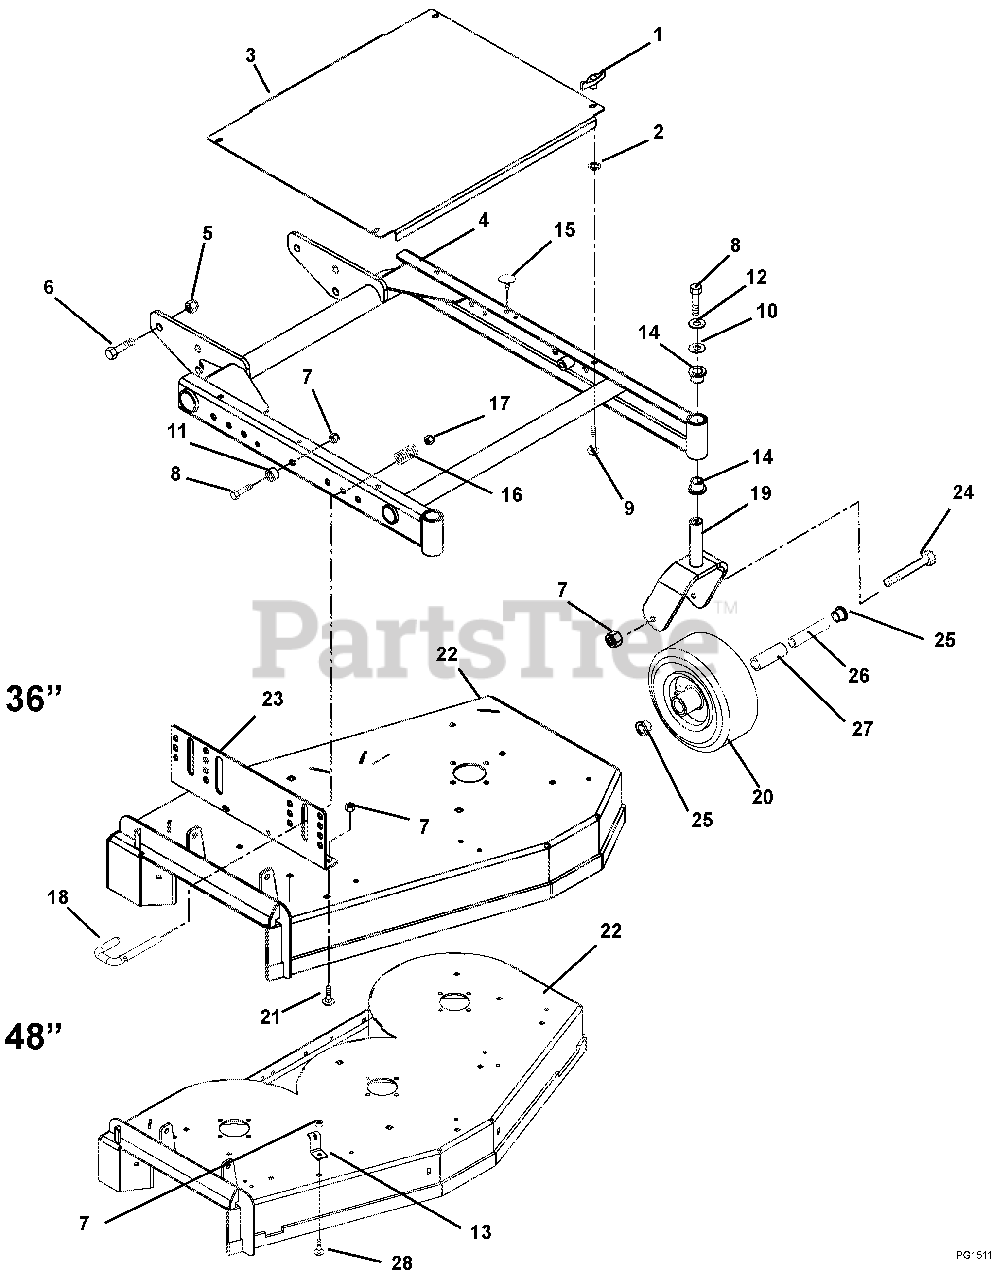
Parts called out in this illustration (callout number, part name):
1	Knob, Wing .312-18 (105, 120, 123, 124)
2	Nut, Push .312 (105, 120, 123, 124)
3	Cover, Belt Pro Mower (105, 120)
4	Weldment, Mower Frame 36" (105, 120)
5	Nut, Locking-Nylon .625-11
6	Bolt, Hex .62-11 x 1.50
7	Nut, Locking-Top-Flange .38-16 (105, 120)
8	Bolt, Hex .38-16 x 1.25 Grade 5
9	Bolt, Round Head Square Neck .31-18 x 1.00 (105, 120, 123, 124)
10	Washer, Flat-Steel .38 x 1.50 x .125
12	Washer, Locking .38 x .094 Regular
13	Anchor, Spring
14	Bushing, Flange 1.00 x 1.25 x 1.50 x 1.50
15	Bumper Grommet .125 x .25 Dia.
16	Spring, Compression .058 x .65 x 2.13
17	Nut, Locking-Center .50-13
18	Pin, Latch
19	Weldment. Caster Fork
20	Wheel 9 x 3.50
21	Bolt, Round Head Square Neck .38-16 x 1.00 Grade (105, 120, 123, 124)
22	Kit, 32" Fixed Mower Deck with Decals
23	Kit, Mower Side Support Bracket-Right Hand and Left Hand
24	Bolt, Hex .38-16 x 5.50
25	Bearing, Retainer
26	Bearing .625 x .380 x 4.08
27	Bearing, Roller
28	Bolt, Round Head Square Neck .38-16 x .75 Grade 5
